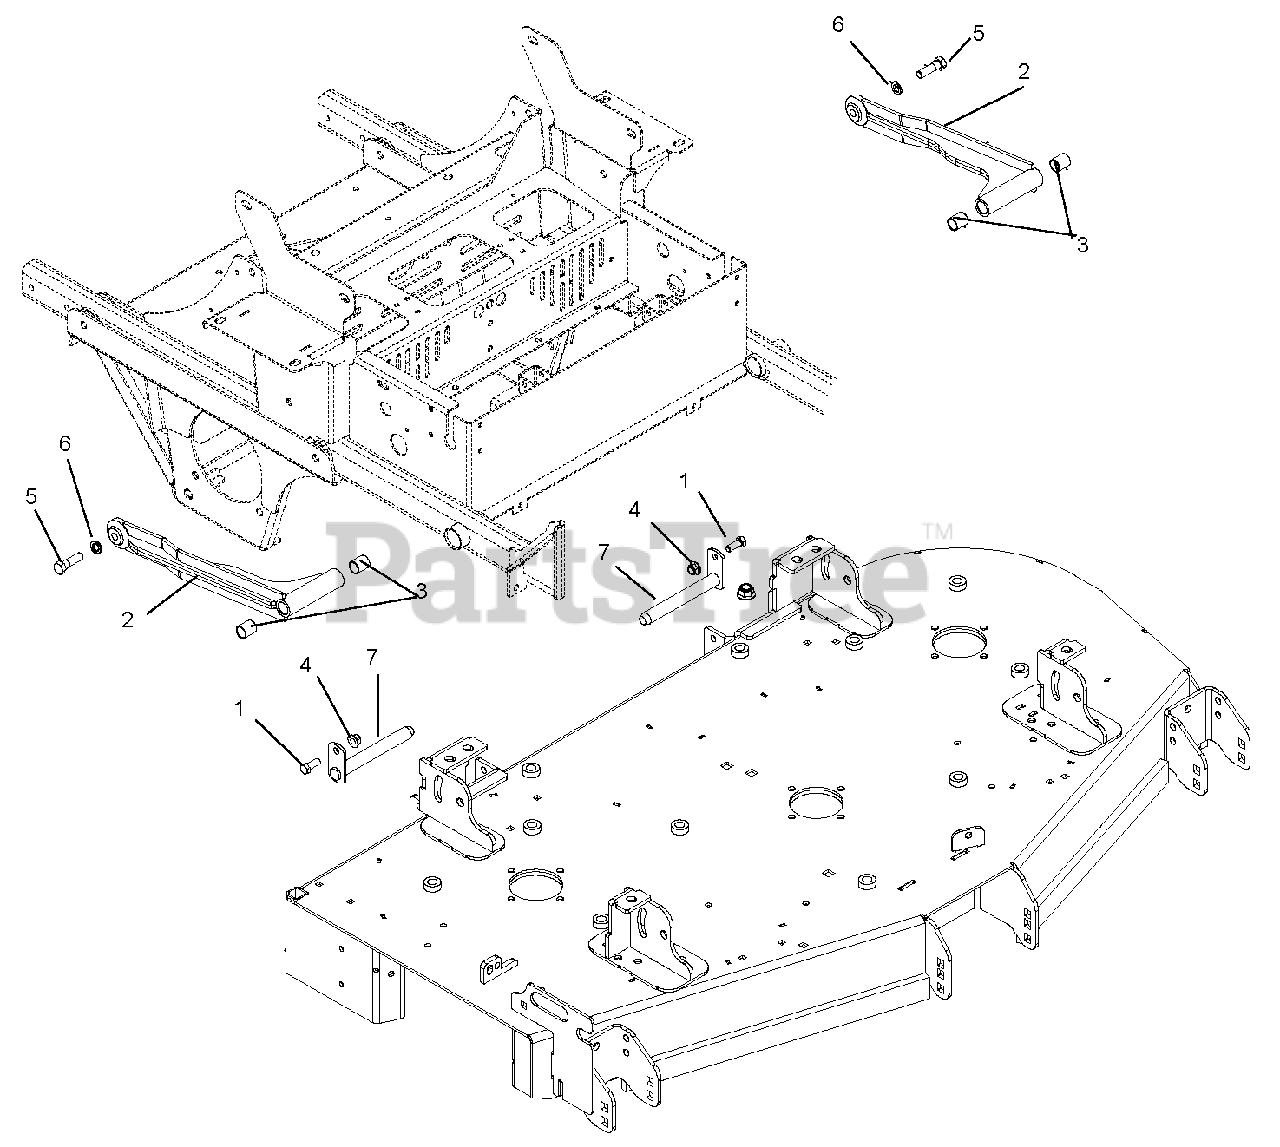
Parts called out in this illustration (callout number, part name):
1	Bolt, Hex .38-16 x 1.00 Grade 5 YWZC
2	Deck Stabilizer Arm – Black
3	Bearing, .75 x .875 x 1.00
4	Nut, Locking Nyloc Flange .38-16
5	Bolt, Hex .50-13 x 1.75 Grade 5 EP80 YZ
6	Washer, Lock .50 x .125 REG YWZC
7	Weldment, Mower Mounting Pin
